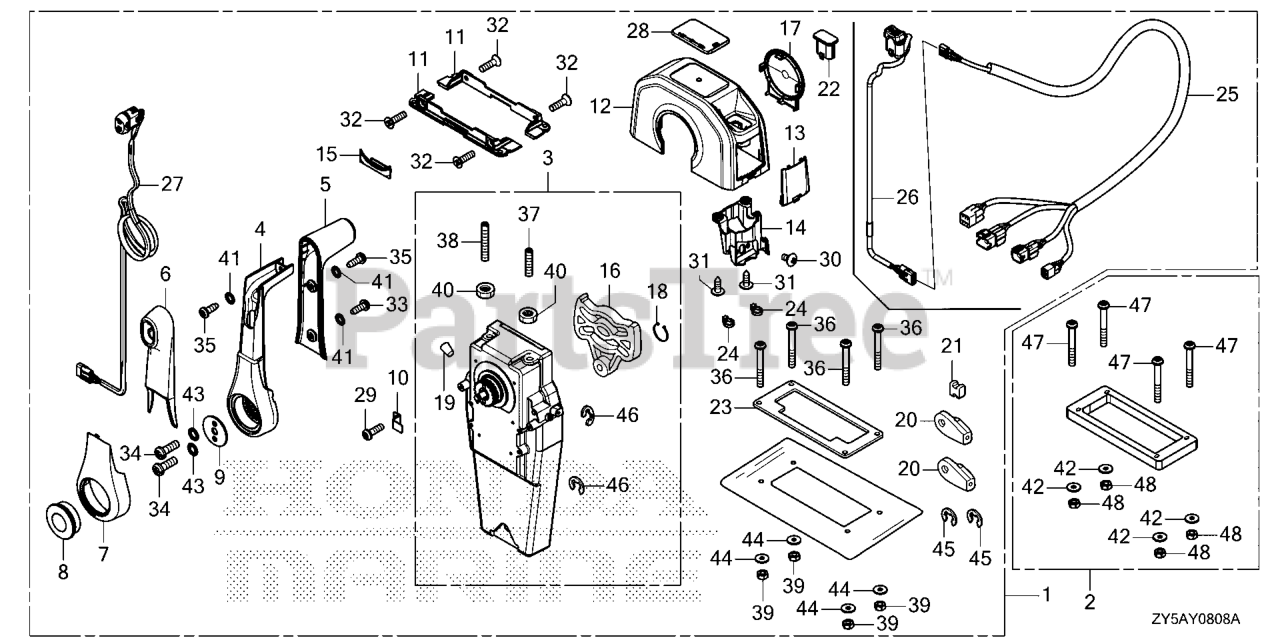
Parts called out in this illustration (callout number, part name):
1	BOX KIT, REMOTE CONTROL (TOP MOUNT SINGLE) (TROLLING CONTROL)
1	BOX KIT, R/C
2	SPACER KIT, REMOTE CONTROL BOX (TOP MOUNT SINGLE)
3	HOUSING ASSY., L. (INNER) (TOP MOUNT) (NOT AVAILABLE)
4	HANDLE, REMOTE CONTROL (NOT AVAILABLE)
5	COVER, GRIP
6	GRIP
7	COVER, LEVER (NOT AVAILABLE)
8	BUTTON, THROTTLE (NOT AVAILABLE)
9	PLATE, HANDLE
10	PLATE, CABLE CLAMP
11	BRACKET, REMOTE CONTROL HOUSING (NOT AVAILABLE)
12	HOUSING, SINGLE REMOTE CONTROL BOX (NOT AVAILABLE)
13	PLUG, SINGLE HOUSING (NOT AVAILABLE)
14	GUIDE, SINGLE WATER (NOT AVAILABLE)
15	HOUSING, LEAD (NOT AVAILABLE)
16	PLATE, DWELL
17	COVER, HOUSING SIDE (NOT AVAILABLE)
18	RING, SNAP (NOT AVAILABLE)
19	GROMMET (NOT AVAILABLE)
20	TERMINAL, CABLE
21	SPACER, CABLE CLAMP
22	CAP, BLANK (NOT AVAILABLE)
23	GASKET, SINGLE
23	GASKET T/S
24	BAND, TY-RAP (POWER TRIM-TILT) (NOT AVAILABLE)
25	HARNESS SUB-ASSY., REMOTE CONTROL (NOT AVAILABLE)
26	SWITCH ASSY., TROLLING CONTROL (NOT AVAILABLE)
27	SWITCH ASSY., POWER TRIM-TILT (NOT AVAILABLE)
28	MARK, REMOTE CONTROL (SINGLE) (NOT AVAILABLE)
29	SCREW, PAN (5X16)
30	SCREW, TRUSS (5X10) (NOT AVAILABLE)
31	SCREW, TRUSS (5X16) (TAPPING) (NOT AVAILABLE)
32	SCREW, PAN (5X18)
33	SCREW, PAN (5X14) (TAPPING) (NOT AVAILABLE)
34	SCREW, PAN (6X18)
35	SCREW, PAN (5X14) (TAPPING)
36	SCREW, PAN (5X40)
37	BOLT, STOPPER (F) (NOT AVAILABLE)
38	BOLT, STOPPER (R) (NOT AVAILABLE)
39	NUT, HEX. (5MM)
40	NUT (6MM) (LOOSE PARTS)
41	WASHER, LOCK (5MM)
42	WASHER, PLAIN (5MM)
43	WASHER, LOCK (6MM)
44	WASHER, PLAIN (5MM)
45	E-RING (6MM) (LOOSE PARTS)
46	E-RING (6MM) (LOOSE PARTS)
47	SCREW, PAN (5X65)
48	NUT, HEX. (5MM)
